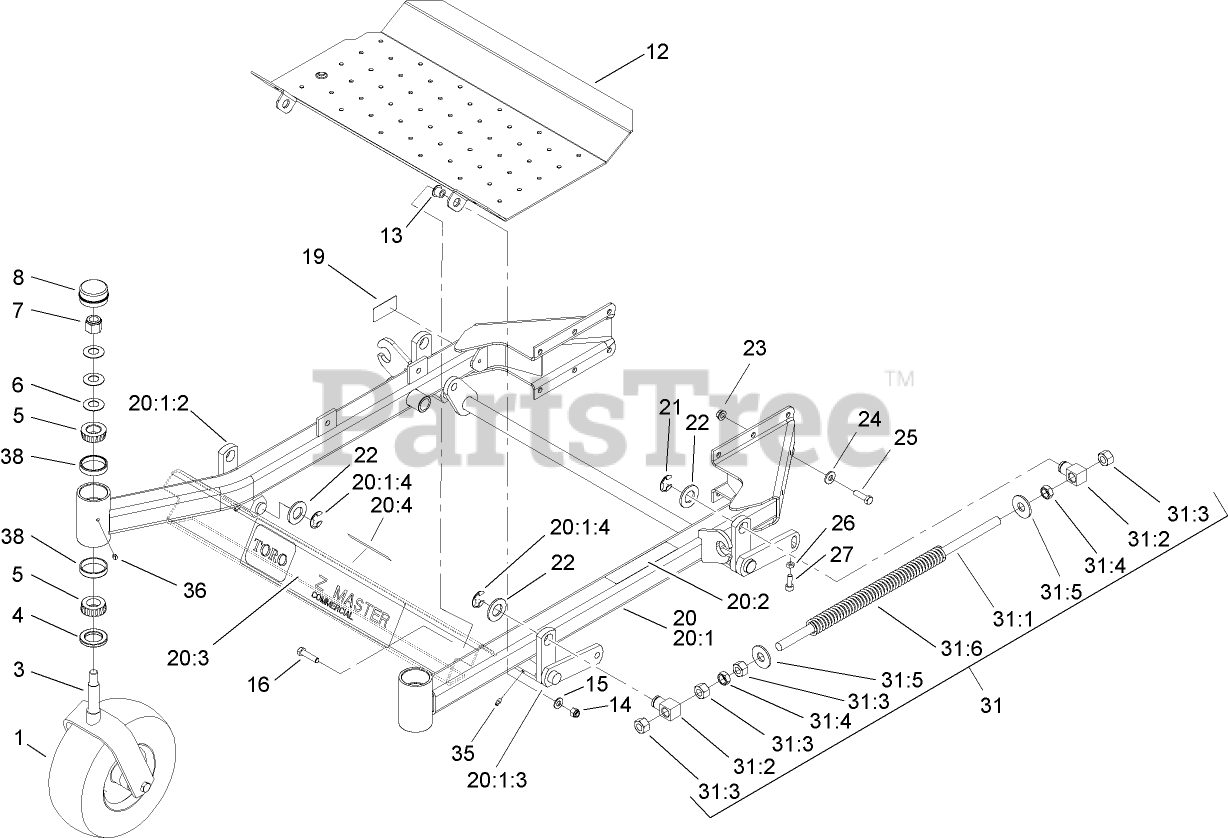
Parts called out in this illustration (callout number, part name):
1	CASTER WHEEL ASM
3	CASTER
4	SEAL-GREASE
5	BEARING-CONE, TAPERED
6	WASHER-BELLVILLE
7	NUT-LOCK, NI
8	CAP-GREASE
12	FLOOR PAN
13	BUSHING-FLANGE
14	NUT-LOCK, NI
15	WASHER-FLAT
16	SCREW-HH
19	DECAL-STD, SAFETY
20	FRONT FRAME ASM
20:1	FRAME-FRONT
20:1:2	RH LIFT ARM ASM
20:1:3	LH LIFT ARM ASM
20:1:4	RING-RETAINING, EXT
20:2	DECAL-WARNING
20:4	DECAL-WARNING
21	RING-RETAINING, EXT
22	WASHER-FLAT
23	NUT-HHF, WHIZ
24	WASHER-BELLEVILLE
25	SCREW-HH
26	NUT-JAM
27	SCREW-HSH
31	FRONT FRAME SPRING ASM
31:1	ROD-LIFT, DECK
31:2	SWIVEL-DECK MOUNT, REAR
31:3	NUT-HEX
31:4	NUT-JAM
31:5	WASHER-FLAT
31:6	SPRING-SUPPORT, DECK
35	FITTING-GREASE
38	BEARING-CUP, TAPERED
